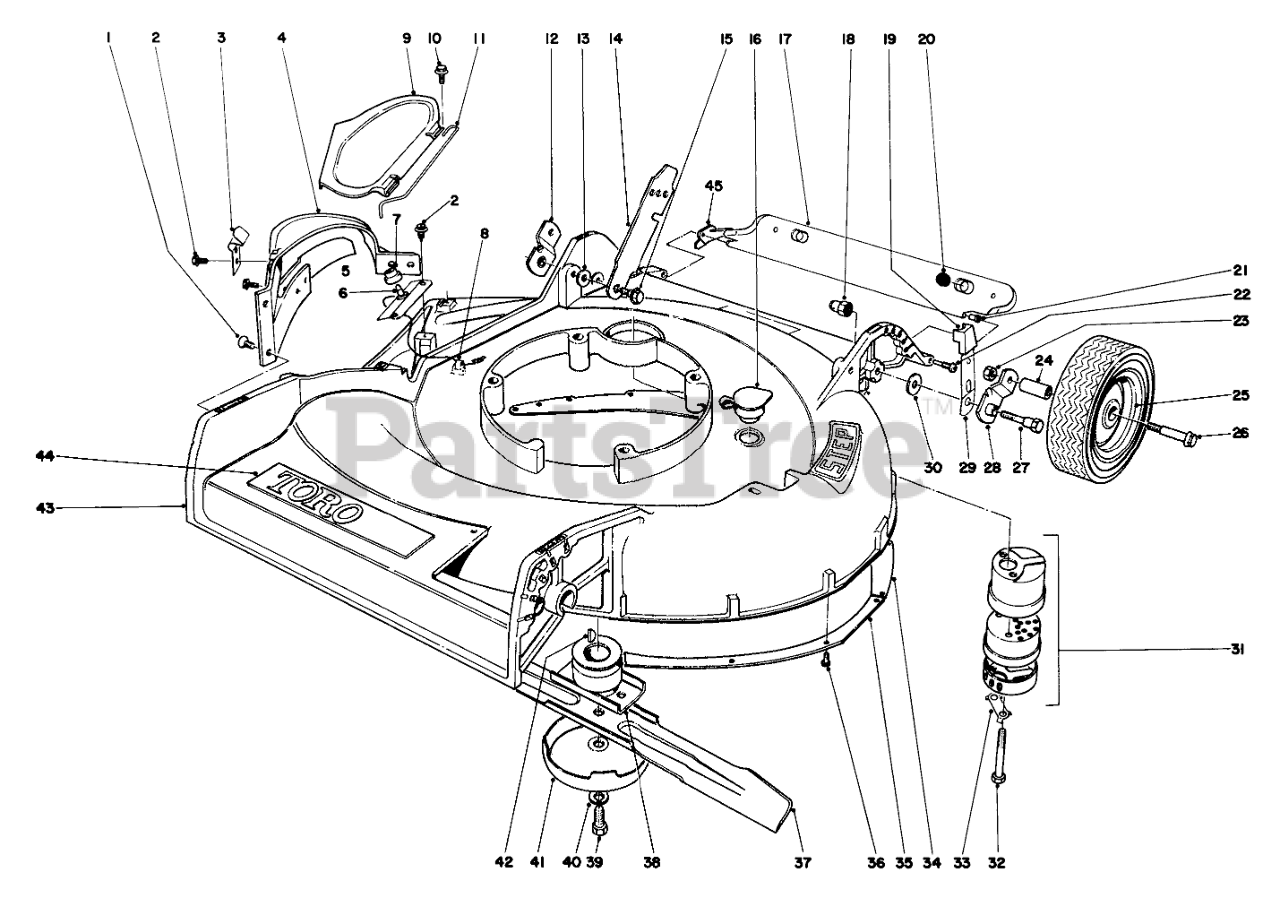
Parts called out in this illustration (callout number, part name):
1	Screw
3	Latch
4	Deflector (Incl. Ref. Nos. 2, 3 & 5)
5	DefIector Bar
6	Deflector Switch & Wire (Incl. Ref. No. 7)
7	Boot Switch
9	Deflector Cover
10	SCREW
11	Hinge Spring
12	Pivot Arm
13	SPACER
14	Latch
15	SCREW-SHOULDER
16	WASHOUT PLUG
17	Safety Shield (Incl. Ref. Nos. 20 & 21)
18	HANDLE PIVOT NUT
19	Knob
20	SKID BUTTON
21	SAFTEY SHIELD BUSHING
22	SAFTEY SHIELD SCREW
23	Nut
24	Bushing
25	Wheel & Tire Assy. (8") (Incl. Ref. No. 24)
27	5/16-18 PIVOT SCREW
28	Pivot Arm
29	Spring Arm
30	WASHER-PIVOT
31	Muffler (Incl. Ref. Nos. 32 & 33)
32	SCREW-HH
33	CLIP - LOCKING
34	Main Skirt
35	Secondary Skirt
37	Blade
38	BLADE RETAINER WA
39	SPECIAL SCREW
40	WASHER-LOCK
41	AntiScalp Cup
42	KEY-WOODRUFF
43	Housing (Incl. Ref. Nos. 34, 35 & 36)
44	Toro Emblem
45	Restraint R.H.
